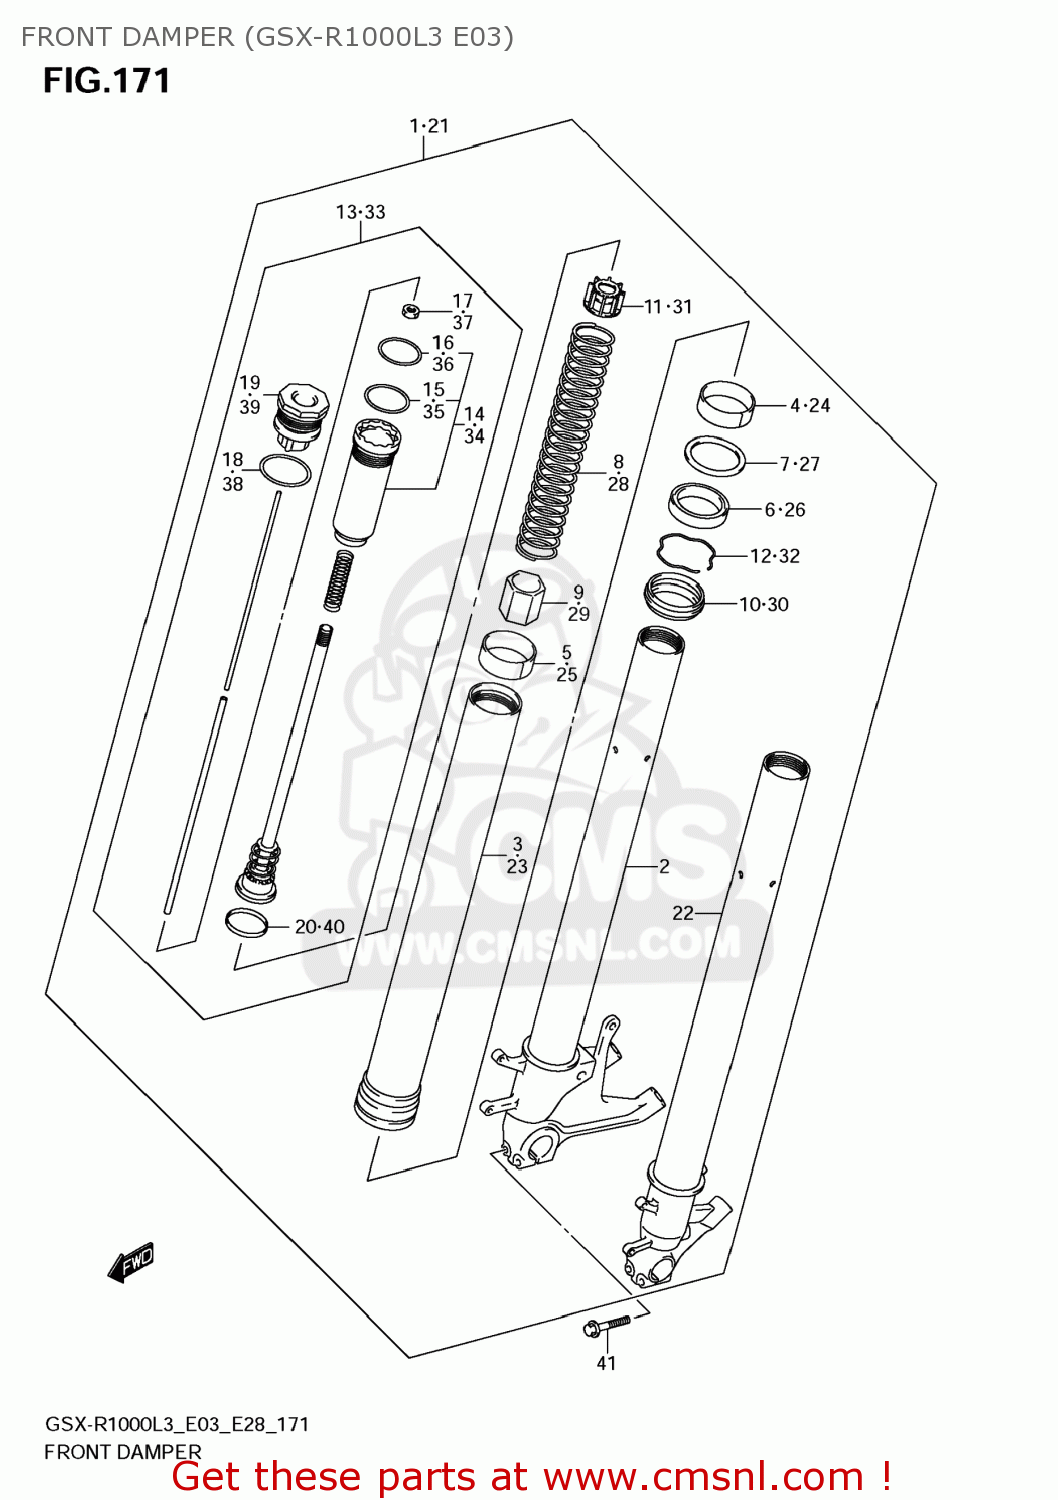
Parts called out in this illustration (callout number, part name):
1	DAMPER ASSY,FR FORK,R
2	TUBE,INNER,R
3	TUBE,OUTER
4	BUSH,GUIDE
5	BUSH,SLIDE
6	SEAL,OIL
7	SPACER,SEAL
8	SPRING
9	COLLAR,SPRING
10	SEAL,DUST
11	COLLAR,SPRING
12	CIRCLIP,FORK OIL SEAL
13	ROD,PISTON
14	CASE,ROD GUIDE
15	RING,PISTON
16	O RING
17	NUT
18	O RING
19	BOLT
20	RING,PISTON
21	DAMPER ASSY,FR FORK,L
22	TUBE,INNER,L
23	TUBE,OUTER
24	BUSH,GUIDE
25	BUSH,SLIDE
26	SEAL,OIL
27	SPACER,SEAL
28	SPRING
29	COLLAR,SPRING
30	SEAL,DUST
31	COLLAR,SPRING
32	CIRCLIP,FORK OIL SEAL
33	ROD,PISTON
34	CASE,ROD GUIDE
35	RING,PISTON
36	O RING
37	NUT
38	O RING
39	BOLT
40	RING,PISTON
41	BOLT
